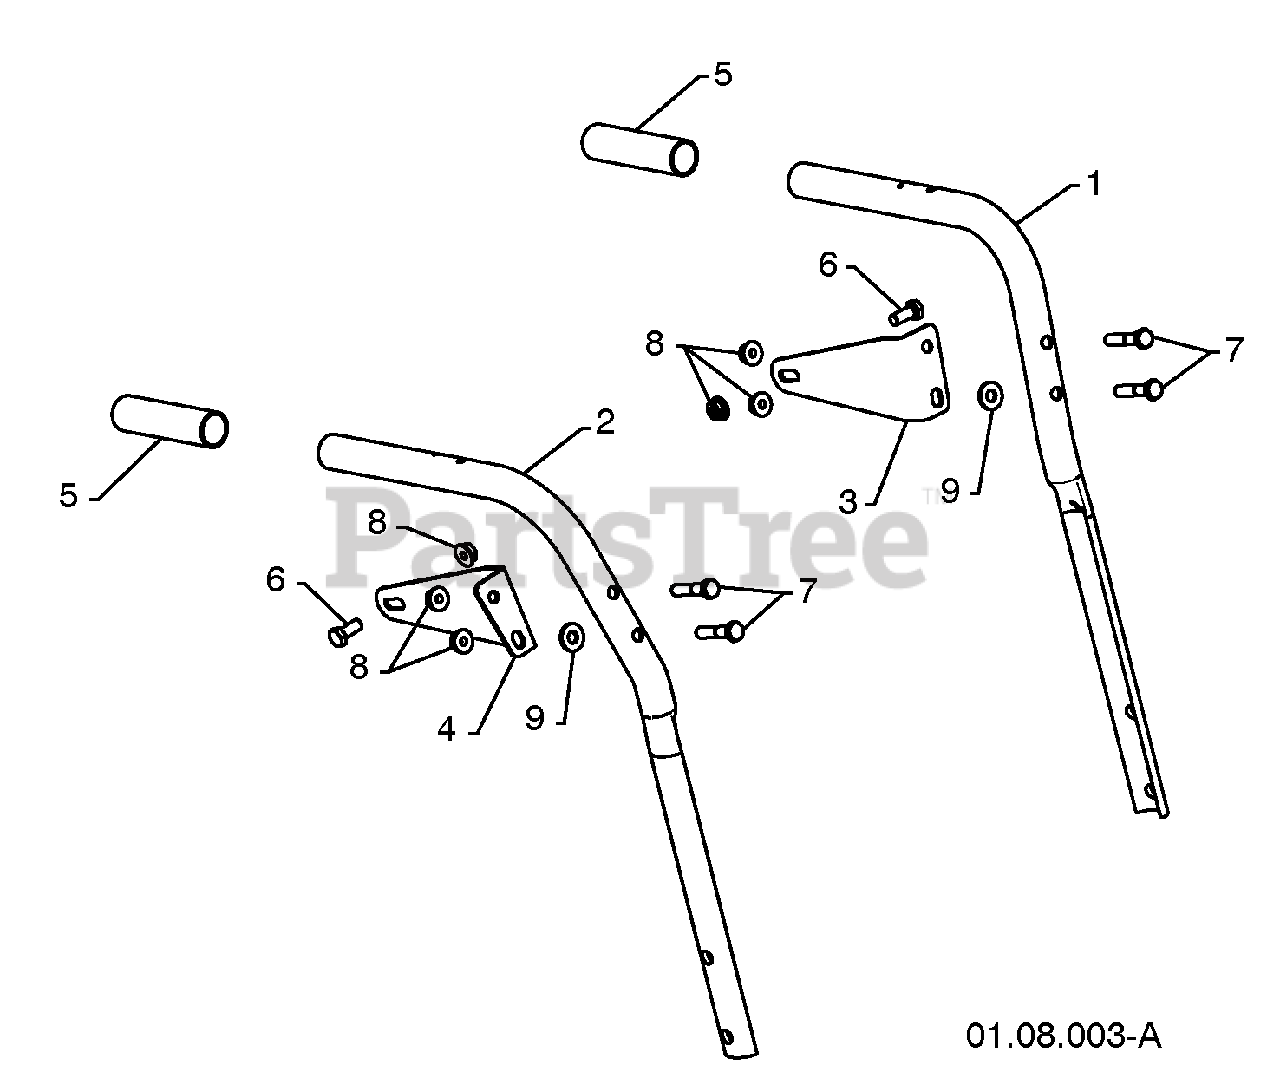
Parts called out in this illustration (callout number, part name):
1	PLOW HANDLE LH
2	PLOW HANDLE RH
3	PANEL BRACKET LH
4	PANEL BRACKET RH
5	HANDLE GRIP
6	SCREW 5/16-18 X .750
7	SCREW 5/16-18 X 1.50
8	NUT 5/16-18
9	WASHER
